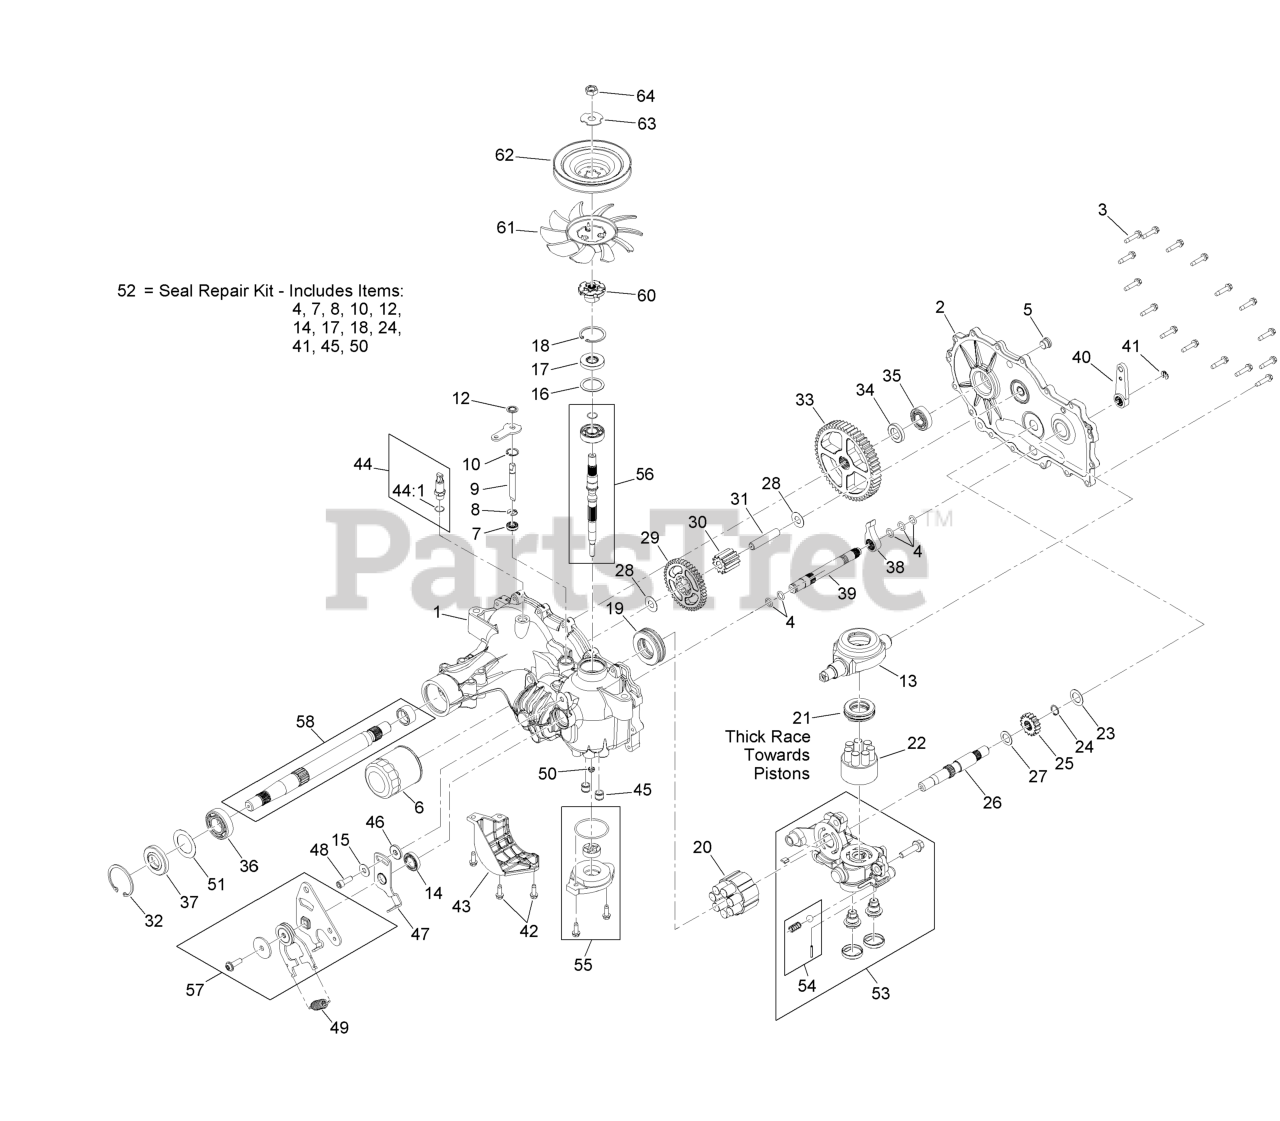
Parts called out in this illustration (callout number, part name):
1	Main Housing Kit
2	RH Housing Side Kit
3	Screw-HHF
5	Plug-Straight
6	Element-Oil Filter, HYD
7	Seal-Lip
8	Ring-Retaining, External
9	Rod-Bypass
10	Ring-Retaining, Internal
12	Ring-Retaining, External
13	Swashplate-Trunnion
14	Seal-Lip
17	Seal-Lip
18	Ring-Retaining
19	Bearing-Thrust
20	Motor Cylinder Block Kit
21	Bearing-Thrust
22	Pump Block ASM
23	Washer-Flat
24	Ring-Retaining
25	Gear-16T
26	Shaft-Motor
29	Gear-43T
30	Gear-11T
31	Pin-Jackshaft
32	Ring-Retaining
33	Gear-54T
35	Bearing-Ball
36	Bearing-Ball
38	Pawl-Brake
39	Shaft-Brake, Inboard
40	Handle-Brake
41	Ring-Retaining, EXT
43	Guard-Filter, RH
44	Adapter-Straight
44:1	O-Ring
45	Tube-Charge
47	Arm-Neutral, Right
48	Screw-Sh
49	Spring-Extension
50	Seal-Gerotor
52	Seal Kit
53	RH Center Section Charge Kit
54	Charge Relief Kit
55	Charge Kit
56	Input Shaft Kit
57	Control Arm Kit
58	Axle Shaft Kit
60	Hub-Pulley
63	Washer-Slotted
